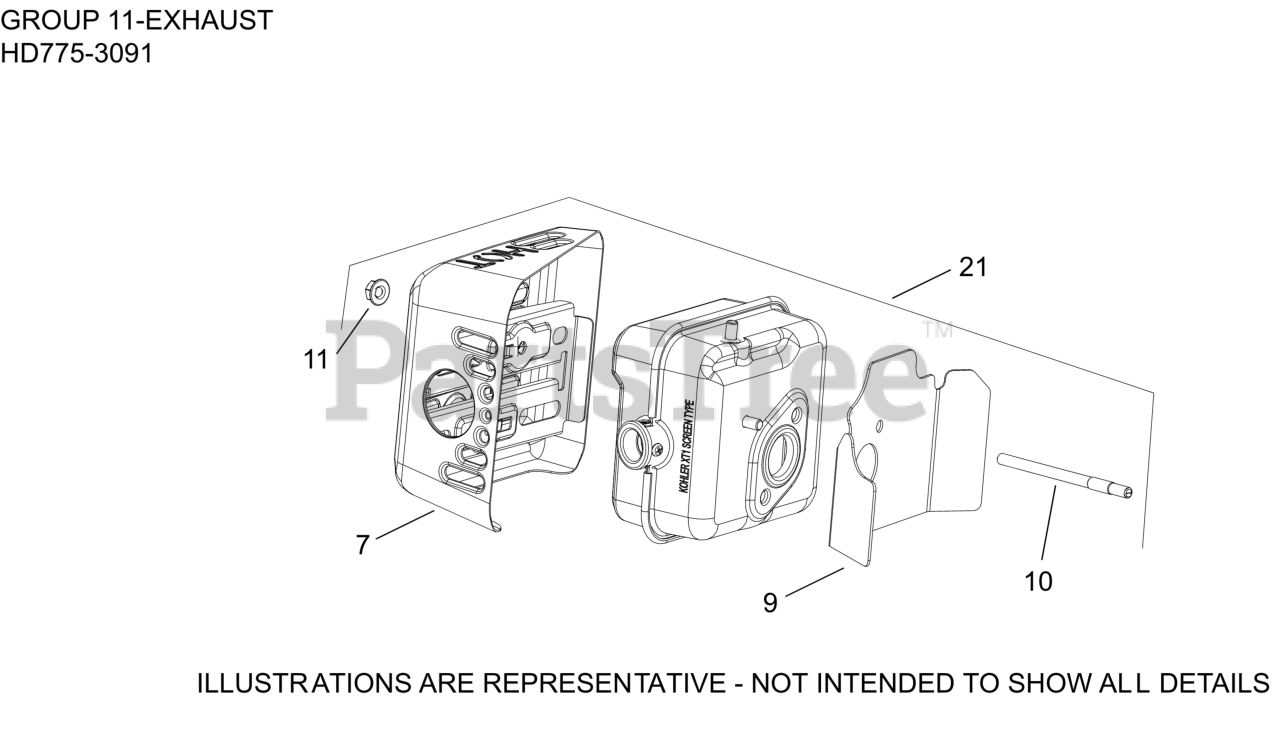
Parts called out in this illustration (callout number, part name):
7	GUARD, MUFFLER ASSEMBLY
9	GASKET, MUFFLER (HEAT DEFLECTOR)
10	STUD, EXHAUST (M6)
11	NUT, HEX FLANGE LOCK (M6)
21	KIT, MUFFLER
